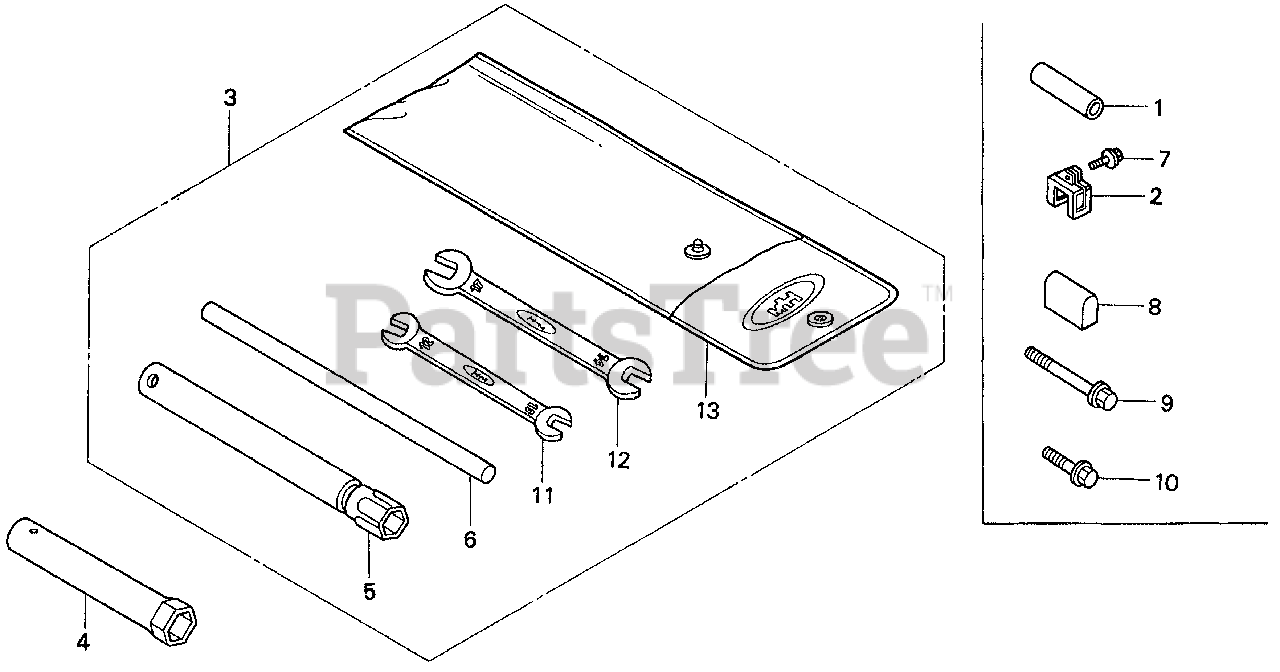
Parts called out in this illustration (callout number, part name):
1	COLLAR (10X16X53)
2	CLIP, WIRE
4	WRENCH, PLUG
7	BOLT, FLANGE (6X12) (CT200)
8	TUBE, WIRE
9	BOLT, FLANGE (8X70)
10	BOLT, FLANGE (8X20)
